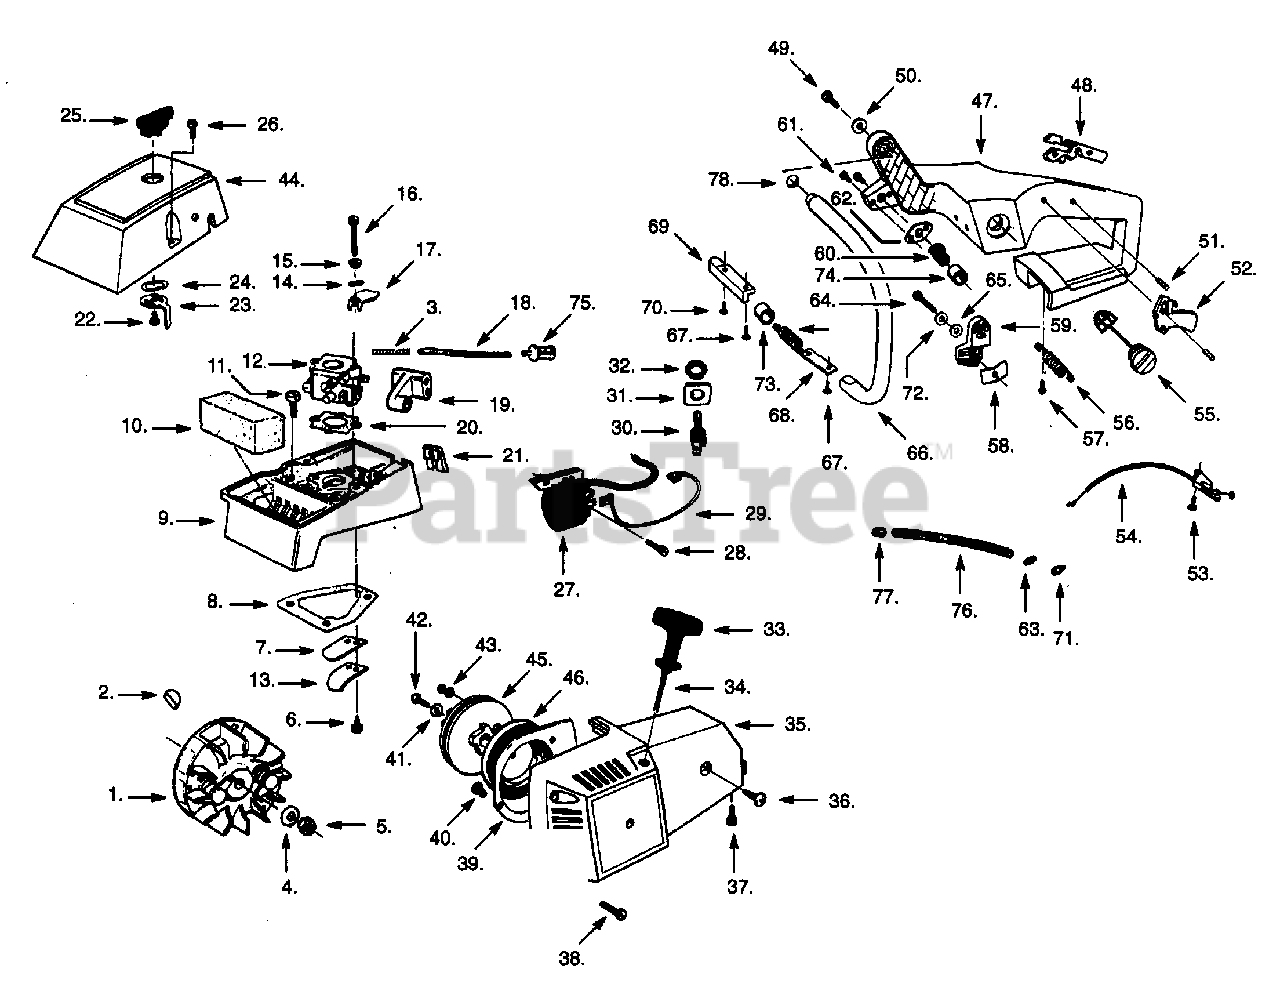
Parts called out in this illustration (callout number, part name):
1	Flywheel Ass'y.
2	Flywheel Key
7	Reed Valve
8	Gasket
9	Carburetor Hsg.
10	Air Filter
12	Carburetor
13	Reed Stop
14	Wave Washer
17	Choke Shutter
18	Line Kit (Bulk#8133)
19	Carb. Adj. Grommet
20	Carb. Gasket
21	Grommet - Throttle Cable
23	Choke Lever
24	Wave Washer
25	Choke Knob
27	Ignition Module
29	Wire Harness
30	Toggle Switch
31	Indicating Plate
32	Nut
33	Starter Handle
34	Rope Kit
35	Fan Hsg.
39	Fan Hsg. Baffle
42	Screw
43	Screw
44	Carb. Cover
45	Starter Pulley
46	Recoil Spring
47	Tank & Handle Assy
48	Throttle Lockout Lever
51	Roll Pin
52	Throttle Trigger
54	Throttle Cable Assy
55	Fuel Cap Assy.
56	Rear Mount Spring
58	Isolator Pad
59	Upper Bracket
62	Isolator Plate
63	Vent Fitting
66	Front Handle
68	AV Strap
69	Isolator Bracket
71	Check Valve
72	Lockwasher
73	Isolator Sleeve
74	Upper Sleeve
75	Fuel Filter Assy
76	Vent Line Kit
77	Vent Plug
